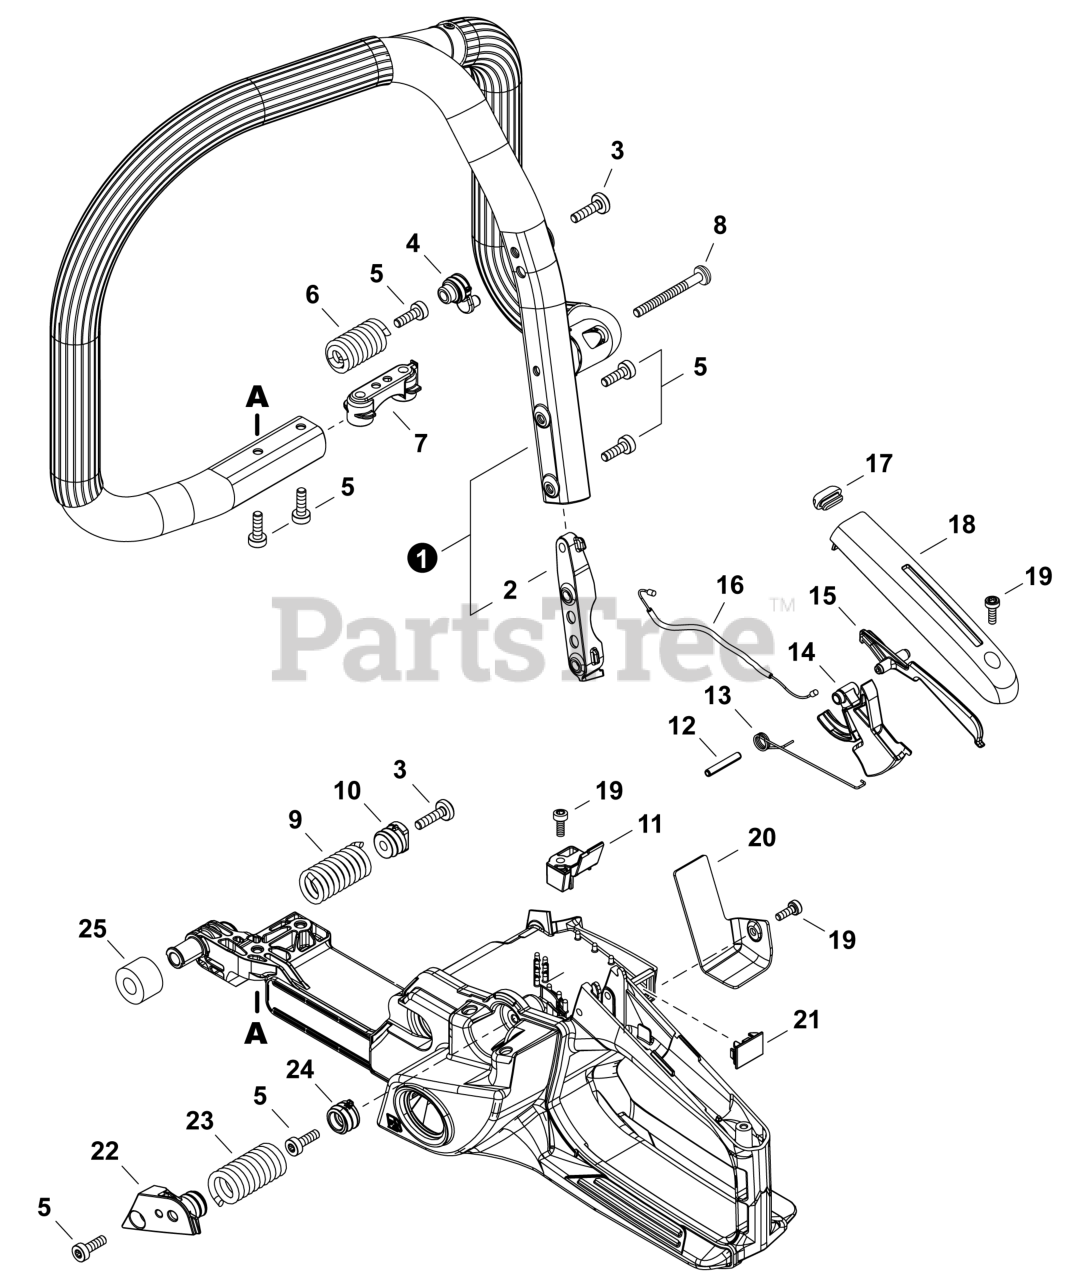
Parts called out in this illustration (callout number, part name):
1	HANDLE, FRONT
2	BRACKET, HANDLE
3	BOLT, TORX 6x20
4	HOLDER, SPRING
5	BOLT, TORX 5x16
6	SPRING, COMPRESSION
7	BRACKET, HANDLE
8	BOLT, TORX 5x50
9	SPRING, COMPRESSION
10	HOLDER, SPRING
11	GUIDE, CABLE
12	PIN, SPRING 4x25 SUS
13	SPRING, TORSION
14	CONTROL, THROTTLE
15	LOCKOUT, THROTTLE
16	CABLE, THROTTLE
17	CUSHION
18	COVER, HANDLE
19	BOLT, TORX 4x12
20	PROTECTOR, CUSHION
21	GROMMET, PLUG
22	HOLDER, SPRING
23	SPRING, COMPRESSION
24	HOLDER, SPRING
25	CUSHION 10
